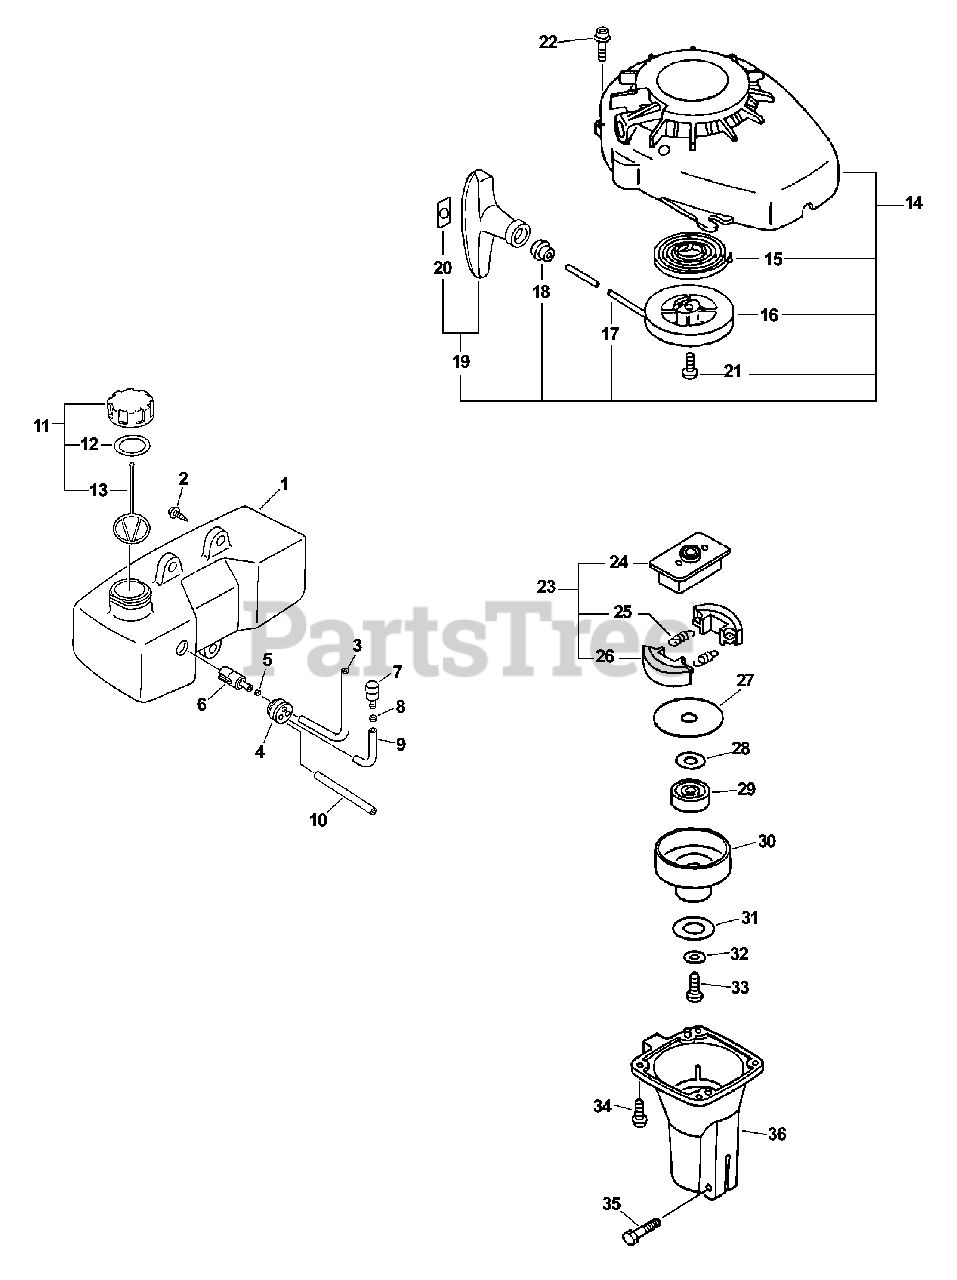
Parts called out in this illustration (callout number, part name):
1	FUEL TANK ASSY
2	SCREW - 5X15
3	PIPE - 3X5X210 -- BLACK
4	GROMMET
5	CLIP - 6
6	FILTER, FUEL
7	VENT, FUEL TANK
8	CLIP - 5.5
9	PIPE - 3X5X70 -- BLACK
10	PIPE - 3X6X50 -- CLEAR
11	CAP ASSY
12	GASKET, CAP
13	CONNECTOR, CAP
14	STARTER ASSY
15	SPRING, REWIND
16	REEL, ROPE
17	ROPE, STARTER - 3X890
18	GUIDE, ROPE
19	GRIP, STARTER
20	RETAINER, ROPE
22	SCREW - 4X16
23	CLUTCH ASSY
24	HUB, CLUTCH
25	SPRING, CLUTCH
26	SHOE, CLUTCH
27	PLATE, CLUTCH
28	WASHER - 10
29	BEARING, BALL - 6000
30	DRUM, CLUTCH
31	WASHER, CLUTCH
32	WASHER, CLUTCH
33	SCREW - 6X12
34	SCREW - 4X14
35	BOLT - 5X25
36	CASE, CLUTCH
